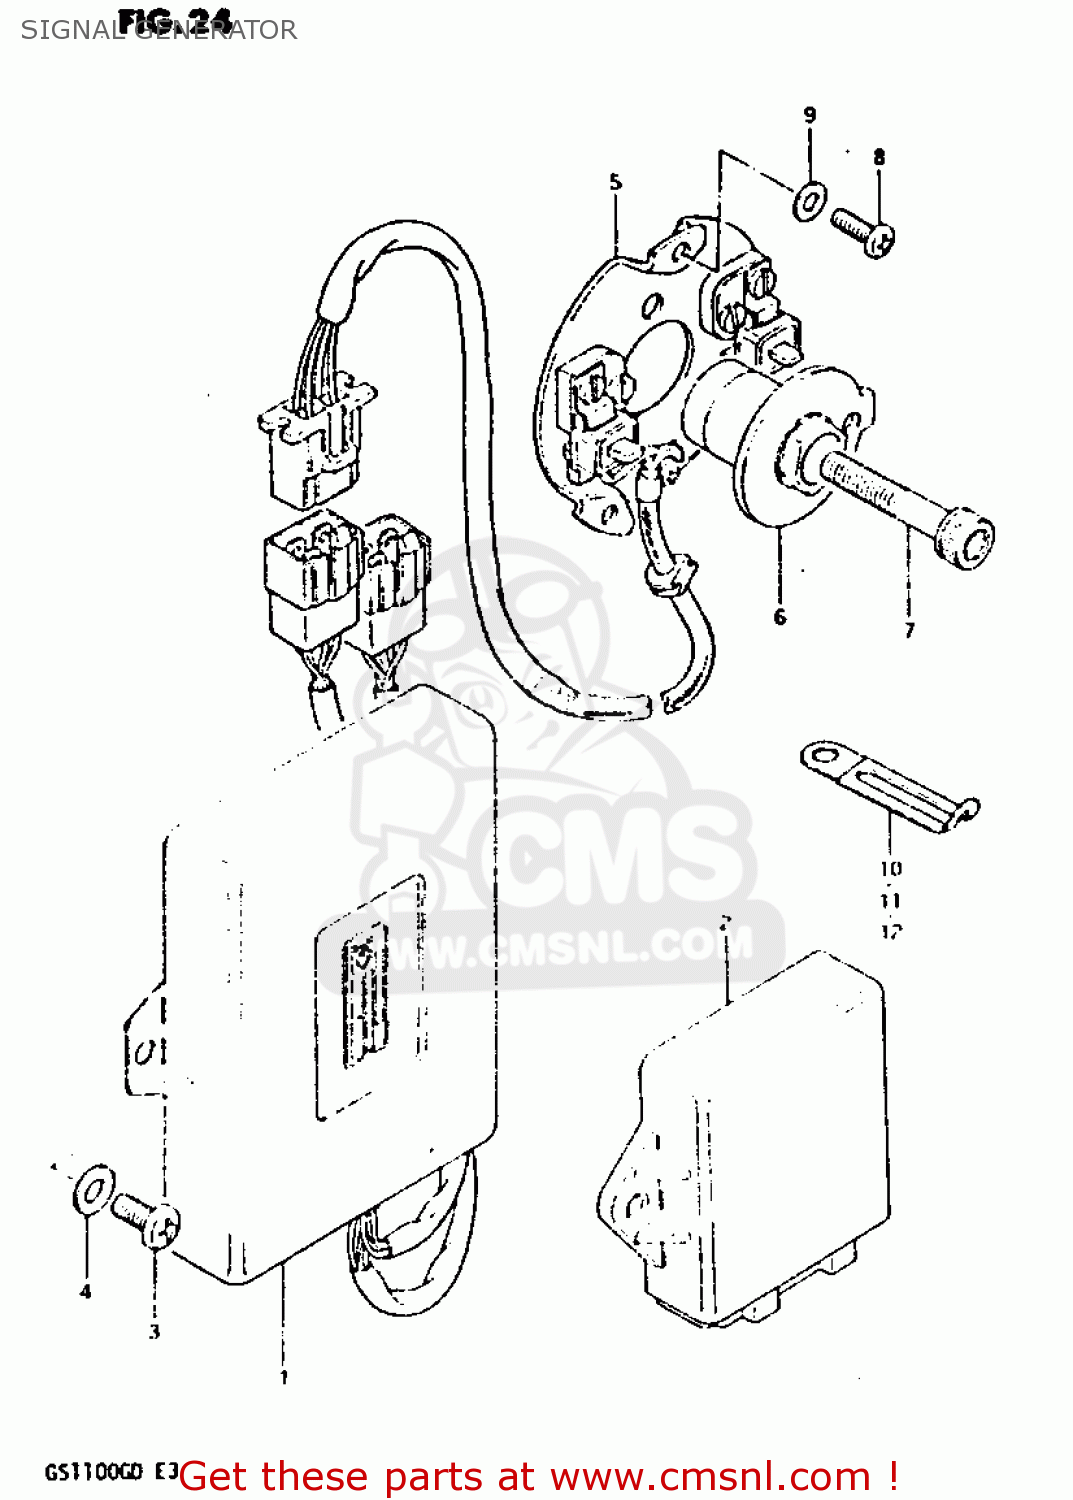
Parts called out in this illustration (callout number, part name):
1	IGNITER UNIT ASSEMBLY
2	IGNITOR UNIT,ESA
3	SCREW 6X12
4	WASHER
5	GENERATOR ASSEMBLY,SIGNAL
6	ROTOR,SIGNAL
7	BOLT 8X45
8	SCREW(5X12)
9	WASHER
10	CLAMP L:35
11	CLAMP
12	CLAMP
